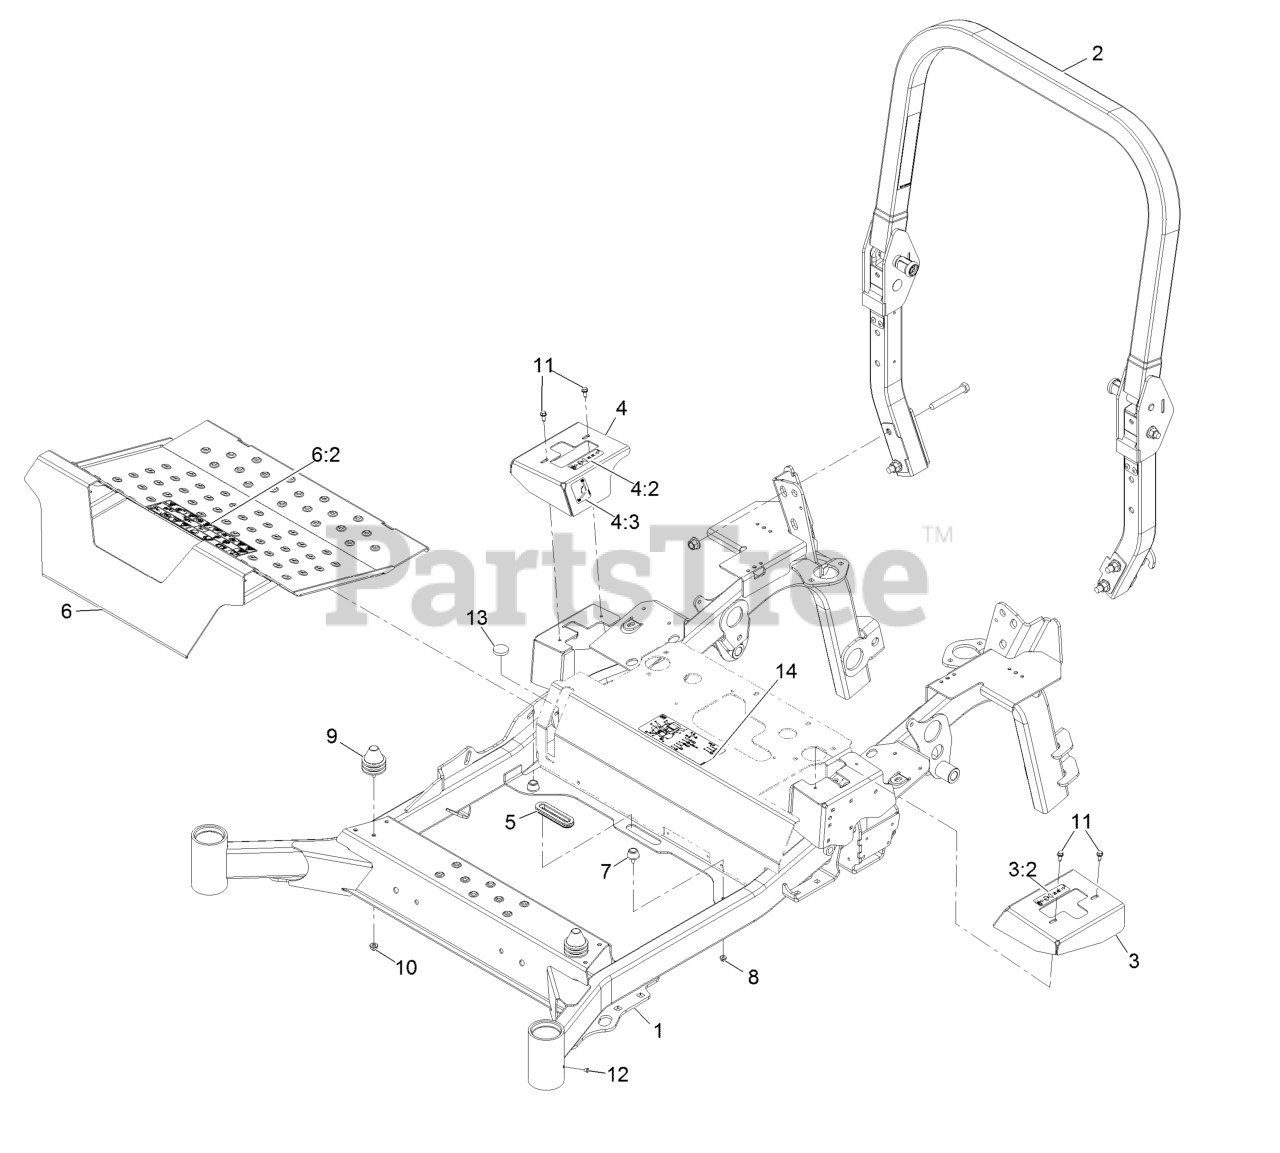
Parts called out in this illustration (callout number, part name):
2	ROPS ASM
3	Cover-Motion Control, LH
3:2	Decal-Control, Motion
4	Cover-Motion Control, RH
4:2	Decal-Control, Motion
4:3	Decal-Park Brake, CE
5	Grommet-Rubber
6	Pan-Floor
6:2	Decal-Danger
7	Bumper-Rubber
8	Nut-Nyloc 1/4-20 Flg
9	Isolator
10	Nut-Nyloc 5/16-18 Flg
11	Screw-HWH 1/4-20 X .62
13	Bumper-Push-In, Rubber
14	Decal-Service Aid
